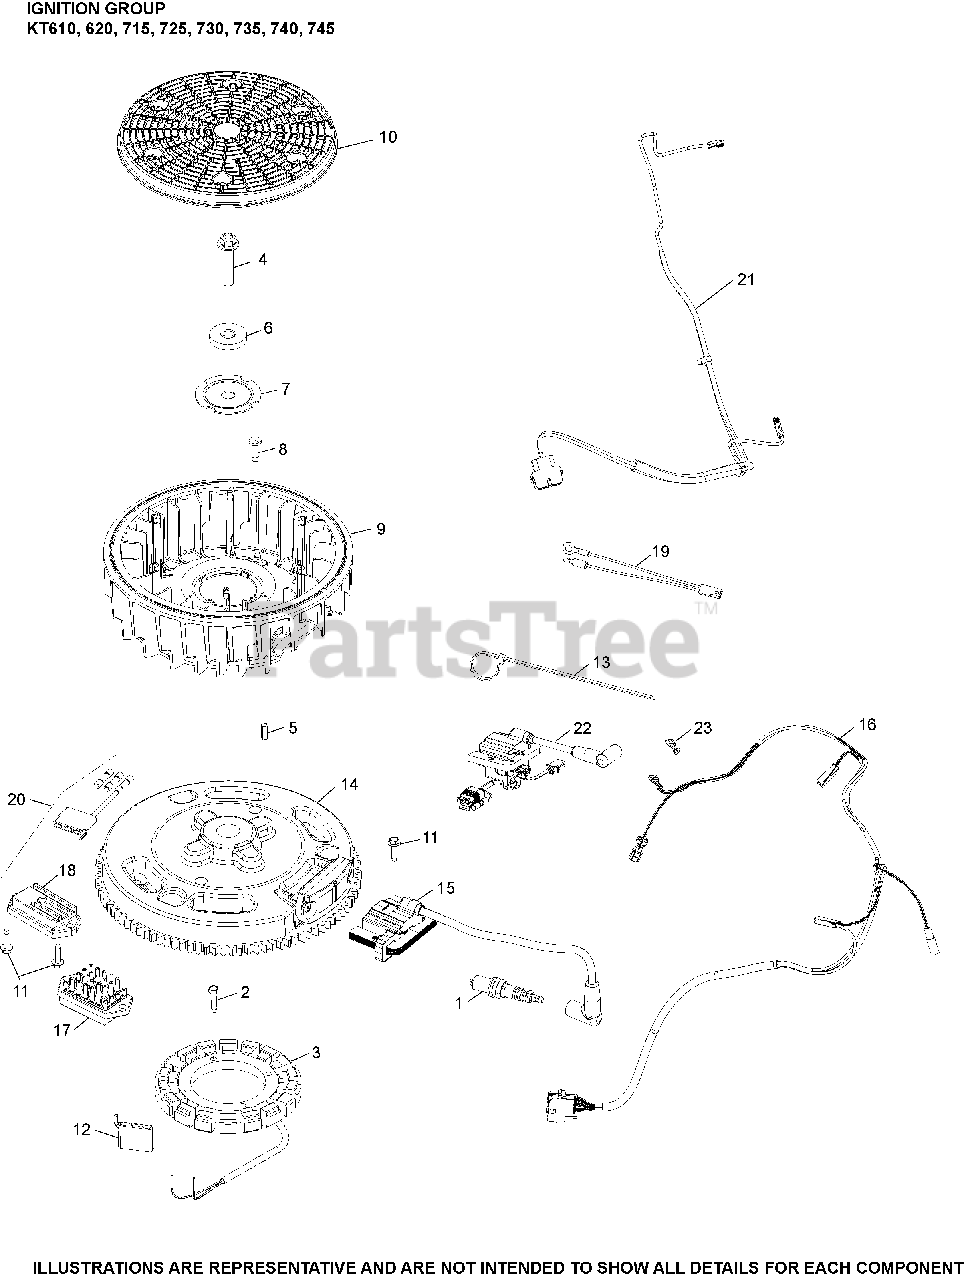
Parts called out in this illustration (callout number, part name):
1	SPARK PLUG, RFI
2	SCREW, THREAD FORMING
3	KIT, 15 / 20 AMP STATOR
4	SCREW, HEX FLANGE
5	KEY, SQUARE
6	WASHER, FLAT
7	PLATE, FAN MOUNTING
8	RETAINER, FLYWHEEL FAN
10	SCREEN, GRASS
11	SCREW, THREAD FORMING - USE 25 086 473-S
12	CONNECTOR
14	FLYWHEEL ASSEMBLY
15	MODULE, IGNITION
16	HARNESS, WIRING ASSEM.W/FUEL SHUT DOWN
18	REGULATOR/RECTIFIER 12/15A HALF-WAVE STD
